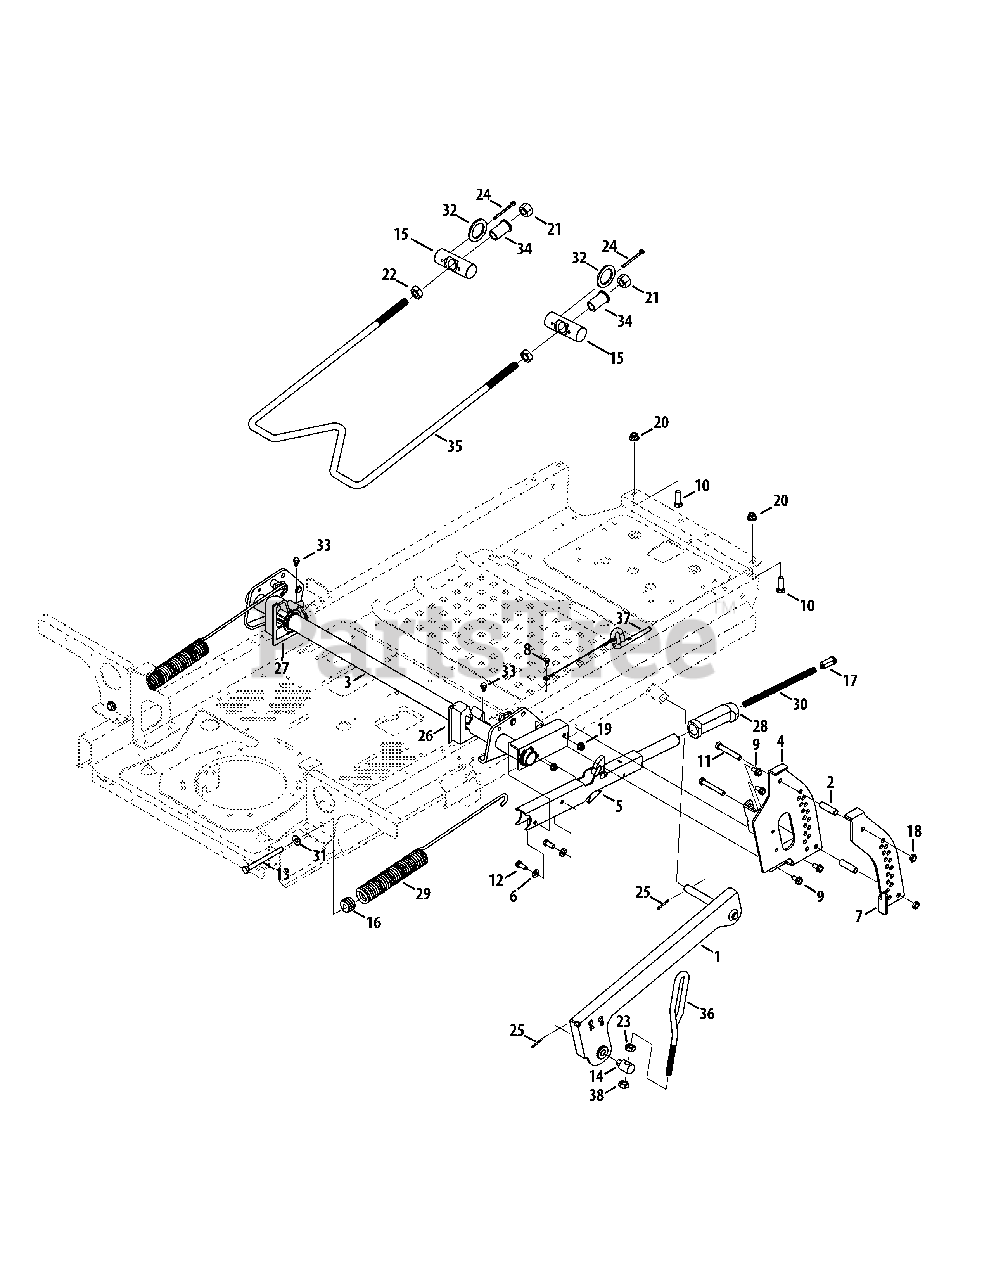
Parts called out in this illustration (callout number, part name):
1	Lift Arm, RH
1	Lift Arm, LH
2	Spacer, .386 x .63 x 1.75
3	Deck Lift Shift Assembly
4	Index Bracket Assembly
5	Latch Handle Assembly
6	Flat Washer .330 ID x .630 OD
7	Outer Index Bracket
8	Screw, #10-16, .50
9	Hex Washer Screw, 5/16-18 x .750
10	Hex Screw, 3/8-16 x 1.00
11	Hex Head Screw, 3/8-16 x 2.50
12	Hex Cap Screw, 5/16-18 x .75
13	Hex Screw, 3/8-16 x 4.25
14	Ferrule, .496 x .528
15	Pivot Pin, 1.25
16	Spring Insert
17	Handle Button
18	Jam Lock Nut, 3/8-16
19	Flange Lock Nut, 5/16-18
20	Flange Lock Nut, 3/8-16
21	Nylock Nut, 5/8-11
22	Jam Nut, 5/8-11
23	Nut, Jam, 1/2-13
24	Cotter Pin, 3/16 x 2.0
25	Cotter Pin 1/8 x 1.25
26	Deck Lift Bracket
27	Deck Lift Bracket, LH
28	Grip, Deck Lift Handle
29	Extension Spring, 1.485 OD x 17.58
30	Spring, Compression, .4 x 8.52
31	Flat Washer, .385 x .870 x .092
32	Flat Washer, 1.875 x 1.38 x .097
33	Shoulder Screw, .500 x 1/4-20
34	Flange Bearing, .875 x .702 x 1.10
35	Deck hanger Rod, 5/8
36	Lift Adjust Link
37	Lock Rod, .375
38	Hex Nut, 1/2-13
